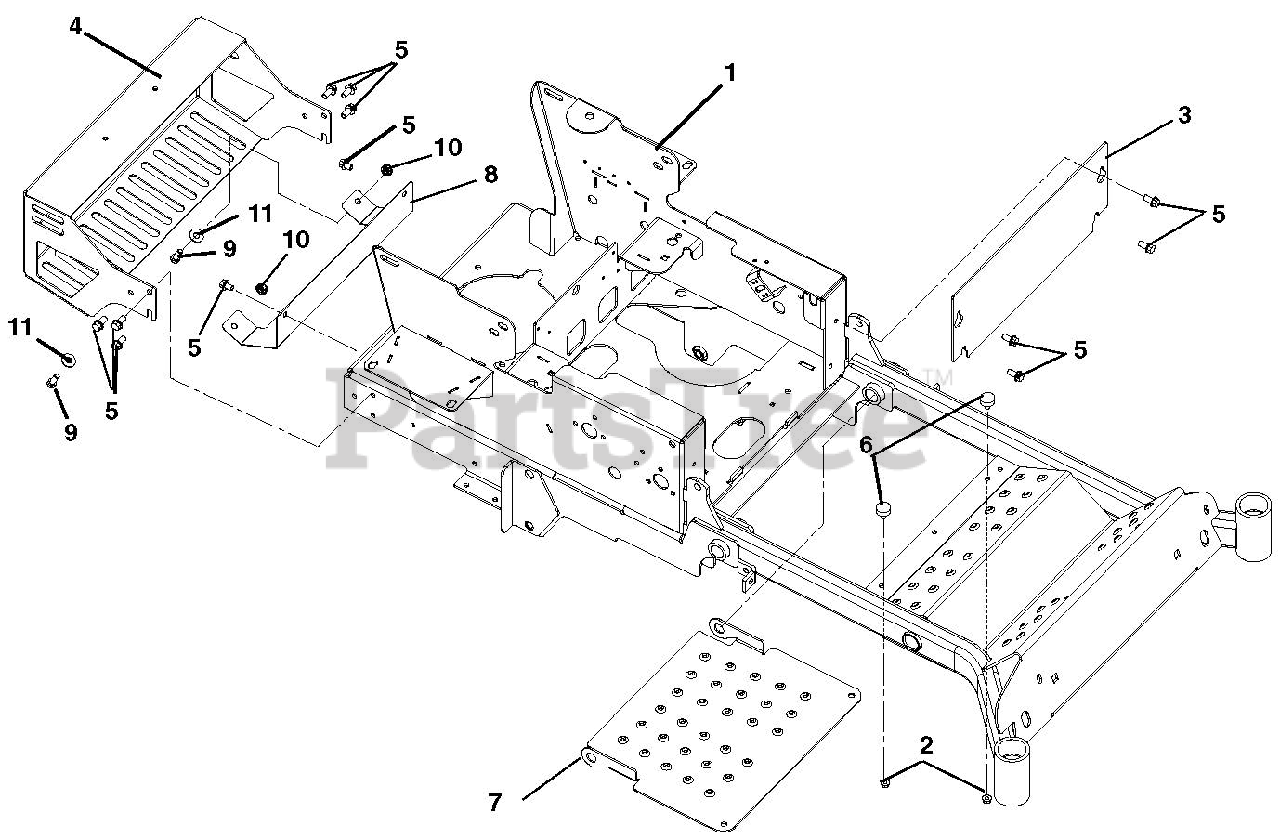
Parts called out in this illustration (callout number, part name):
1	52-60" MAIN FRAME - BLACK
2	@NUT-SPNLK-FLG .312-18 YWZC
3	PLATE, KICK
4	ARIENS ZOOM HD BUMPER WMT -BLK
5	@SCR-TAP .38-16X.75 HWH TR YWZ
6	BUMPER, RUBBER
7	PANEL, INSPECTION
8	SHIELD - HEAT - CZ PROD
9	@BLT-HEX .38-16X1.00 GR5 YWZC
10	@NUT-LK-NYL-FLG .38-16 YWZC
11	@WSHR-FL-STL.438X1.00X.083 YWZ
